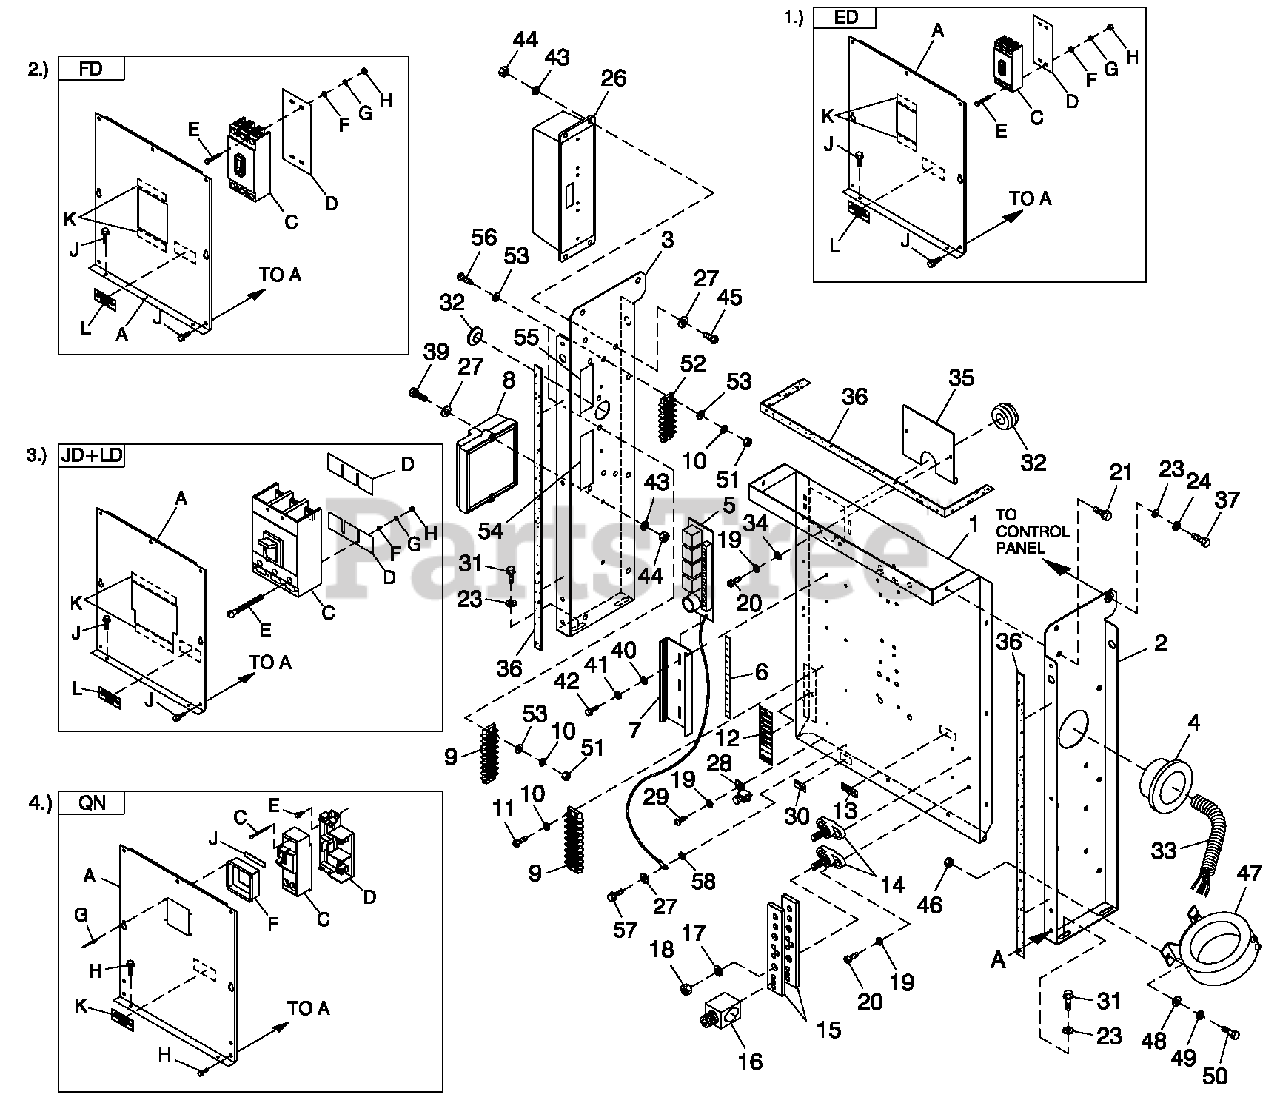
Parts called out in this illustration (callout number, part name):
1	PAN CB CONN BOX
1	UL CIRCUIT BREAKER (ED)
2	STAND RH CONTROL
2	UL CIRCUIT BREAKER (FD)
3	STAND LH CONTROL HPNL
3	UL CIRCUIT BREAKER (JD+LD)
4	BUSHING SNAP SB-2.5-31
4	UL CIRCUIT BREAKER (QN)
5	ASSY RELAY PCB12VDC
6	DECAL SPARE OUTPUT
7	RAIL SNAPTRACK PCB HOLDER BULK
8	ASSY PCB IGNITION MODULE 2.4L
9	BLOCK TERM 20A 8 X 6 X 1100V
10	WASHER LOCK #6
11	SCREW PHTT #6-32X1/2 ZYC
12	DECAL CPL CUST CONN H CTRL
13	DECAL NEUTRAL
14	JUNCTION BLOCK 3/8-16
15	BUS BAR NEUTRAL BLOCK 390
16	LUG SLDLSS 600/250-1/0 X 1/4-28
17	WASHER LOCK 3/8
18	NUT HEX 3/8-16 STEEL
19	WASHER LOCK M5
20	SCREW PHTT M5-0.8X 16 ZYC
21	SC REW THFM6-1X16NWA Z/JS
23	WASHER FLAT 1/4-M6 ZINC
24	WASHER LOCK M6-1/4
26	INTERFACE 3PH 416/480V
27	WASHER FLAT #10 ZINC
28	LUG SLDLSS #6-14X 13/64 CU
29	SCREW HHTT #10-32X3/8 CZ
30	DECAL GROUND LUG
31	SCREW HHTT M6-1.0X16ZYC
32	GROMMET 1.25 X .25 X .75
33	CONDUIT FLEX 2.0" ID (36" LG)
34	WASHER FLAT M5
35	PLATE WIRE SNGLGALV
36	TAPE ELEC 1/2 FOAM (AS REQ'D)
37	SCREW HHC M6-1.0X 16 G8.8
39	SCREW PPHM #10/32X2
40	WASHER FLAT M4
41	WASHER LOCK #8-M4
42	SCREW PHTT M4-0.7X 10 ZYC
43	WASHER LOCK #10
44	NUT HEX #10-32 STEEL
45	SCREW PRHM #10-32X1/2
46	NUT HEX M6 X 1.0 G8 YEL CHR
47	XFMRCURRENT 200AW/BRKT (120/240 1P)
48	WASHER FLAT 1/4-M6 ZINC
49	WASHER LOCK M6-1/4
50	SCREW HHC M6-1.0X16G8.8
51	NUT HEX #6-32 STEEL
52	BLOCK TERM 20A 6 X 6 X 1100V
53	WASHER FLAT #6 ZINC
54	DECAL H-100 IFT
55	DECAL EXCITER
56	SCREW RHM #6-32X3/4
57	SCREW HHTT M4-0.7X8ZP
58	WASHER SHAKEPROOF EXT #10 STL
A	COVER ED CB SHORT STND
C	CB 0050A 3P 480V S ED4 LL
D	INSULATOR CBS(ED-3P)
E	SCREW RHM #10-32X4-1/2
F	WASHER FLAT #10 ZINC
G	WASHER LOCK #10
H	NUT HEX #10-32 STEEL
J	SC REW THFM6-1X16NWA Z/JS
K	TAPE ELEC 1/2 FOAM (AS REQ'D)
L	DECAL CUSTOMER CONNECT INSIDE
A	COVER CB CONN BOX
C	CB0150A 3P 600V SFD6 LL
D	INSULATOR CB FD FRAME 30MIL
E	SCREW SHC 1/4-20 X 4.5 G8.8 NZ
F	WASHER FLAT 1/4-M6 ZINC
G	WASHER LOCK M6-1/4
H	NUT HEX 1/4-20 STEEL
J	SCREW THF M6-1 X 16 N WA Z/JS
A	COVER JD/LD CB SHRT STAND
C	CB0300A 3P 600V SJD6 LL
D	INSULATOR CIRCUIT BR. JD/LD
E	SCREW RHM 1/4-20X3
A	COVER QN FRM CB
C	CB0150A 2P 240V SQN2 LL
D	BASE, QN CIRCUIT BREAKER
E	SCREW HHTT M5-0.8X 10 BP
F	COVER QN CB DISH
G	RIVET POP .125 X .275 SS
H	SCREW THF M6-1X16 N WA Z/JS
J	TAPE ELEC 1/2 FOAM (AS REQ'D)
K	DECAL CUSTOMER CONNECT INSIDE
